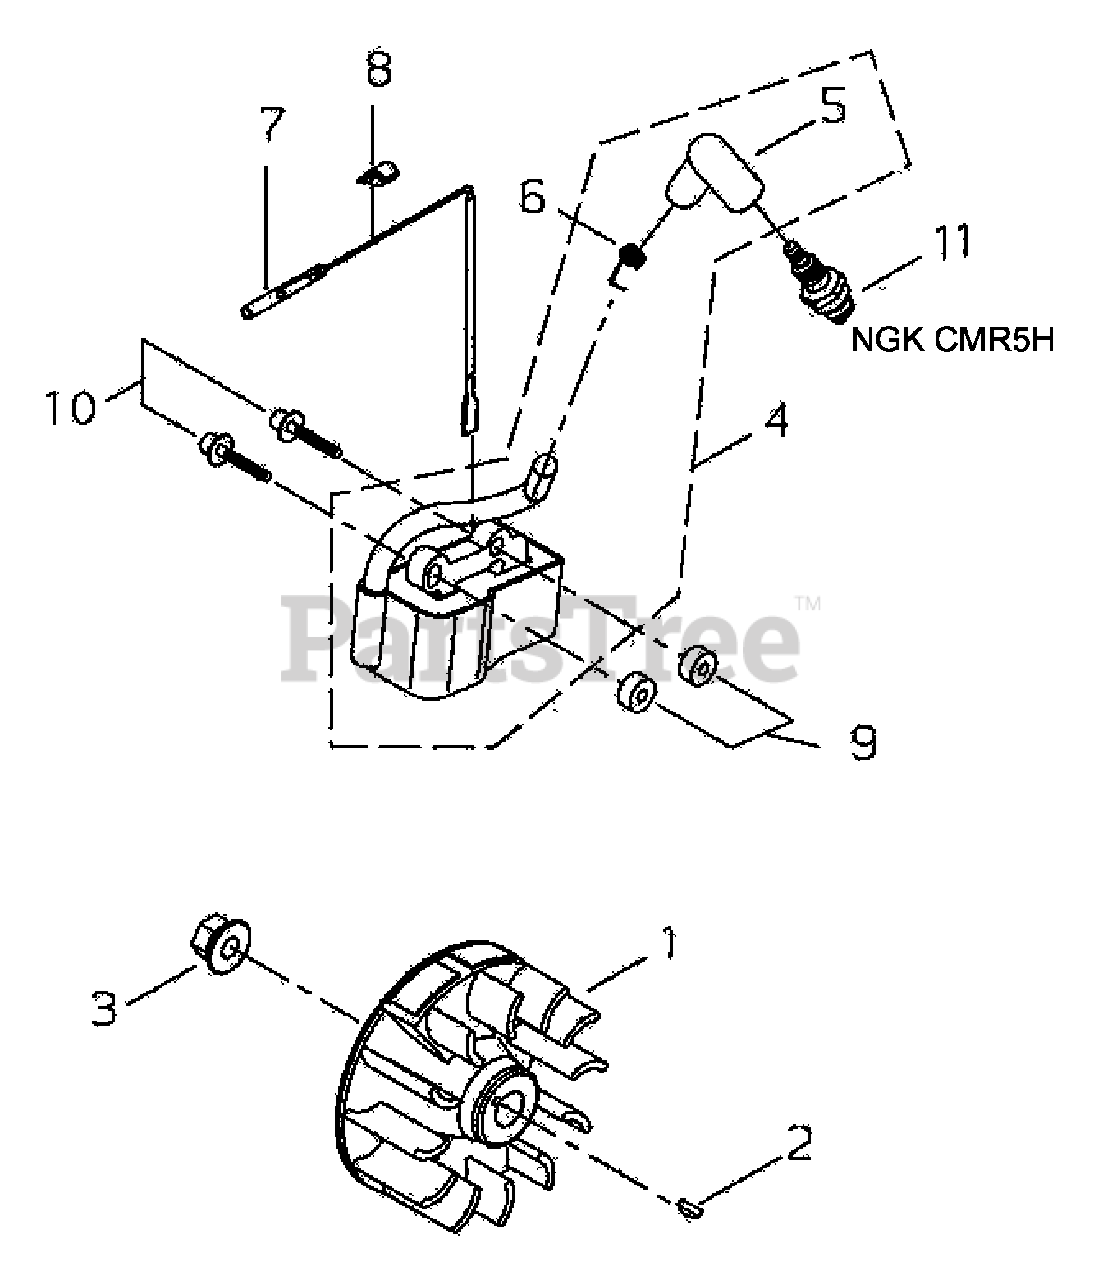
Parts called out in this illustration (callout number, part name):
1	FLYWHEEL
2	KEY - 3X10
3	NUT - 8
4	IGNITION COIL ASSY
5	IGNITION COIL ASSY
6	TERMINAL, SPARK PLUG CAP
7	LEAD - IGNITION
8	GROMMET
9	INSULATOR
10	SCREW - 4X26
11	SPARK PLUG -- CMR-5H
